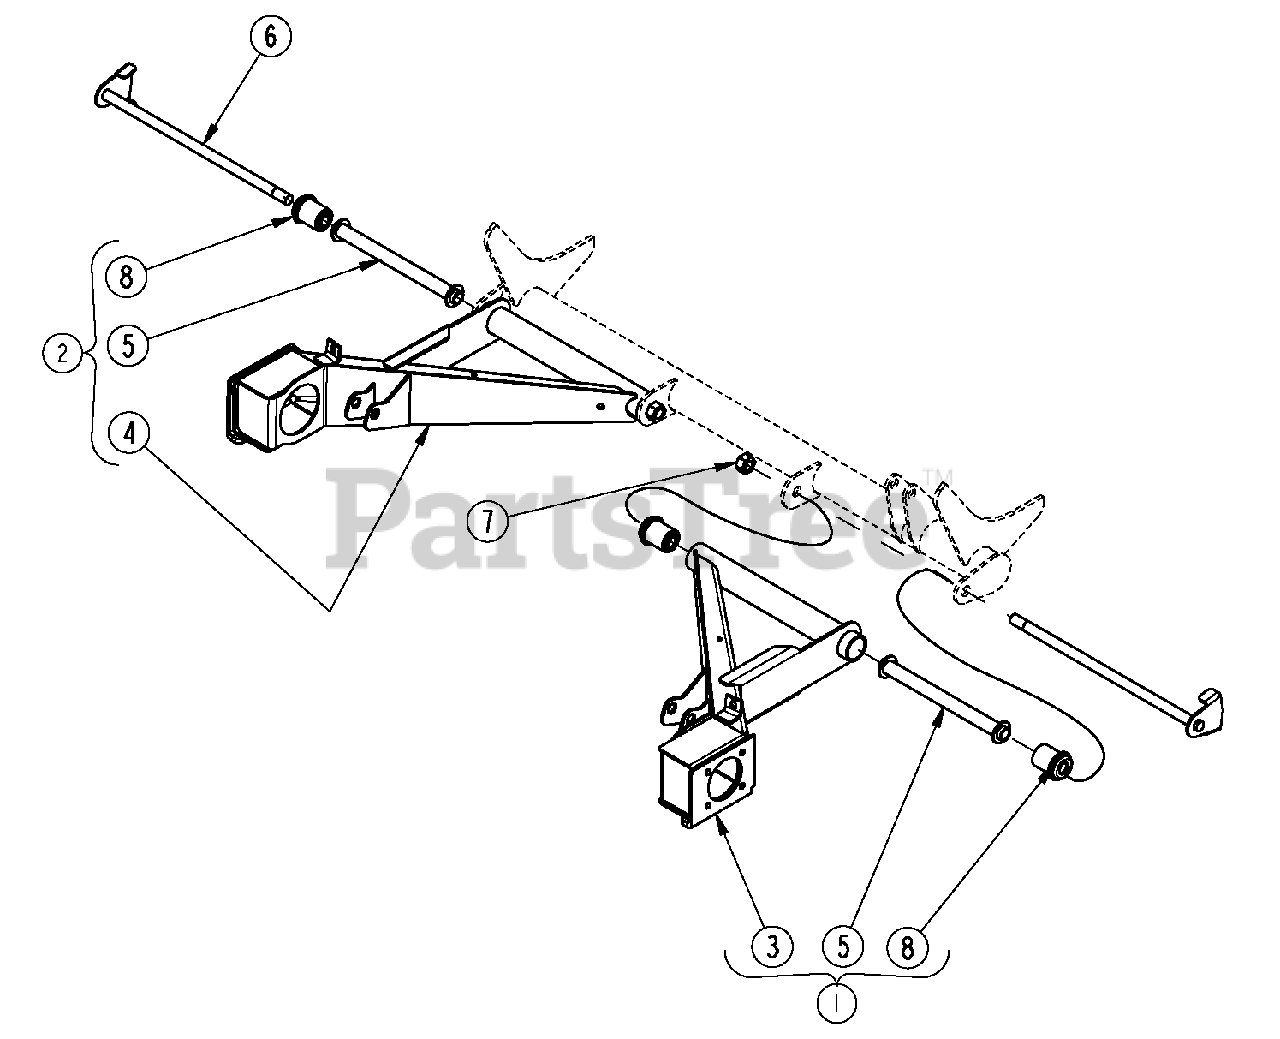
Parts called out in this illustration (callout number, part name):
1	TRAILING ARM RH ASSY
2	TRAILING ARM LH ASSY
3	TRAILING ARM RH WELDMENT
4	TRAILING ARM LH WELDMENT
5	CENTER PIVOT TUBE WELDMENT
6	TRAILING ARM PIVOT BOLT WLDMNT
7	NUT-LK-TOP .563-12 GR5 YWZC
8	BUSHING IDLER ARM RUBBER
